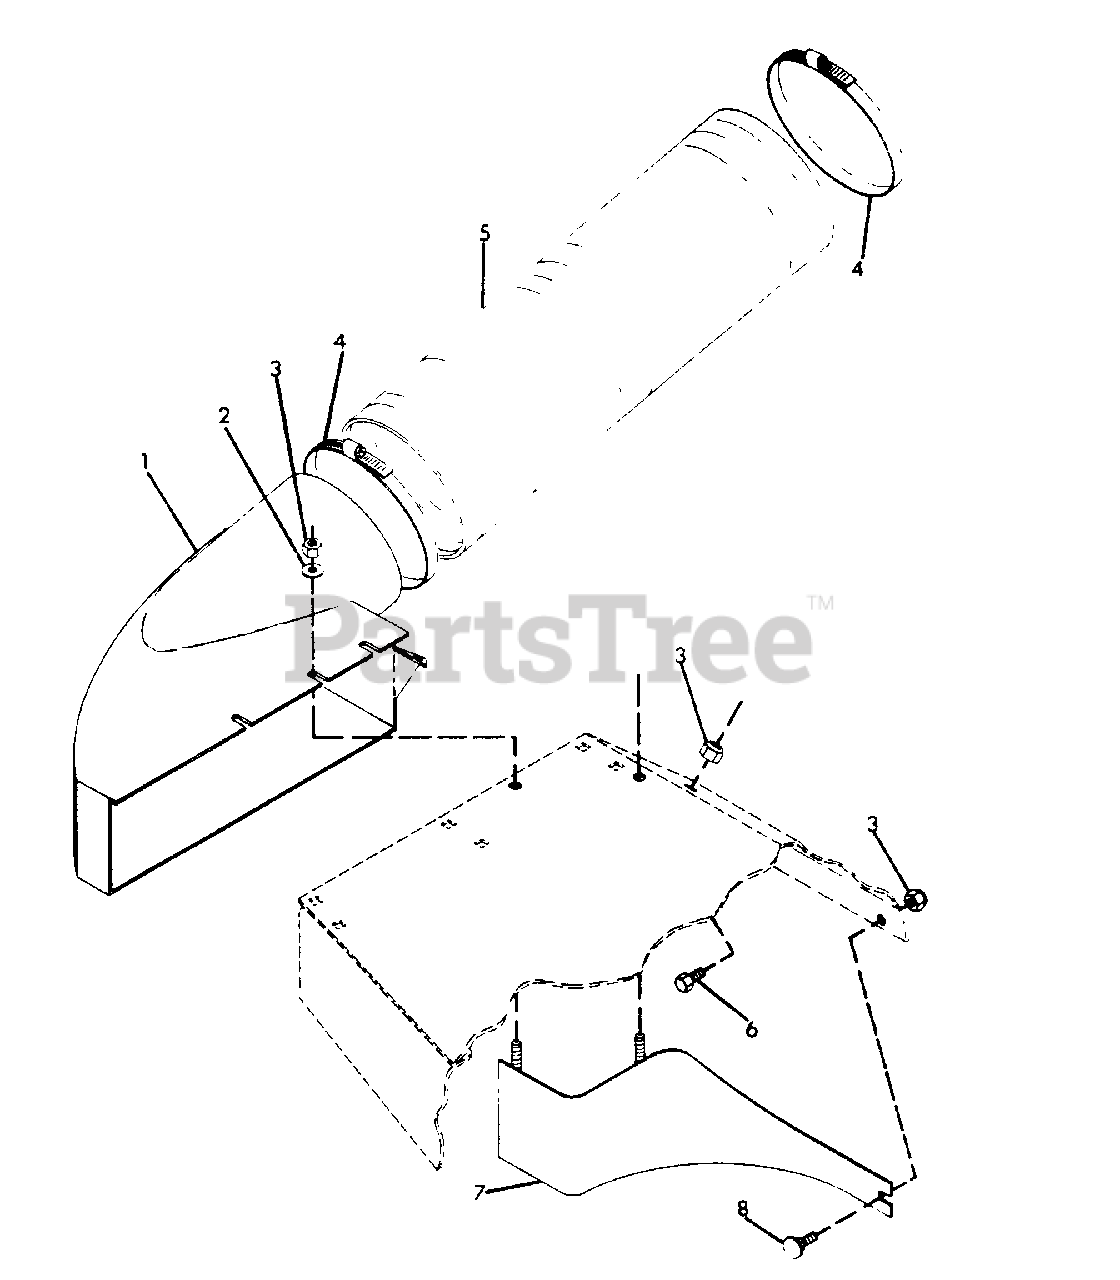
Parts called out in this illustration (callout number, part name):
1	CHUTE, 60" DISCHARGE
2	WASHER, FLAT .406X.812X.065
3	NUT, LOCK 3/8-16
4	CLAMP
5	HOSE, MOWER TO BLOWER
6	BOLT, HEX 3/8-16X1
7	WELDMENT, BAFFLE
8	BOLT, CARRIAGE 3/8-16X.75
